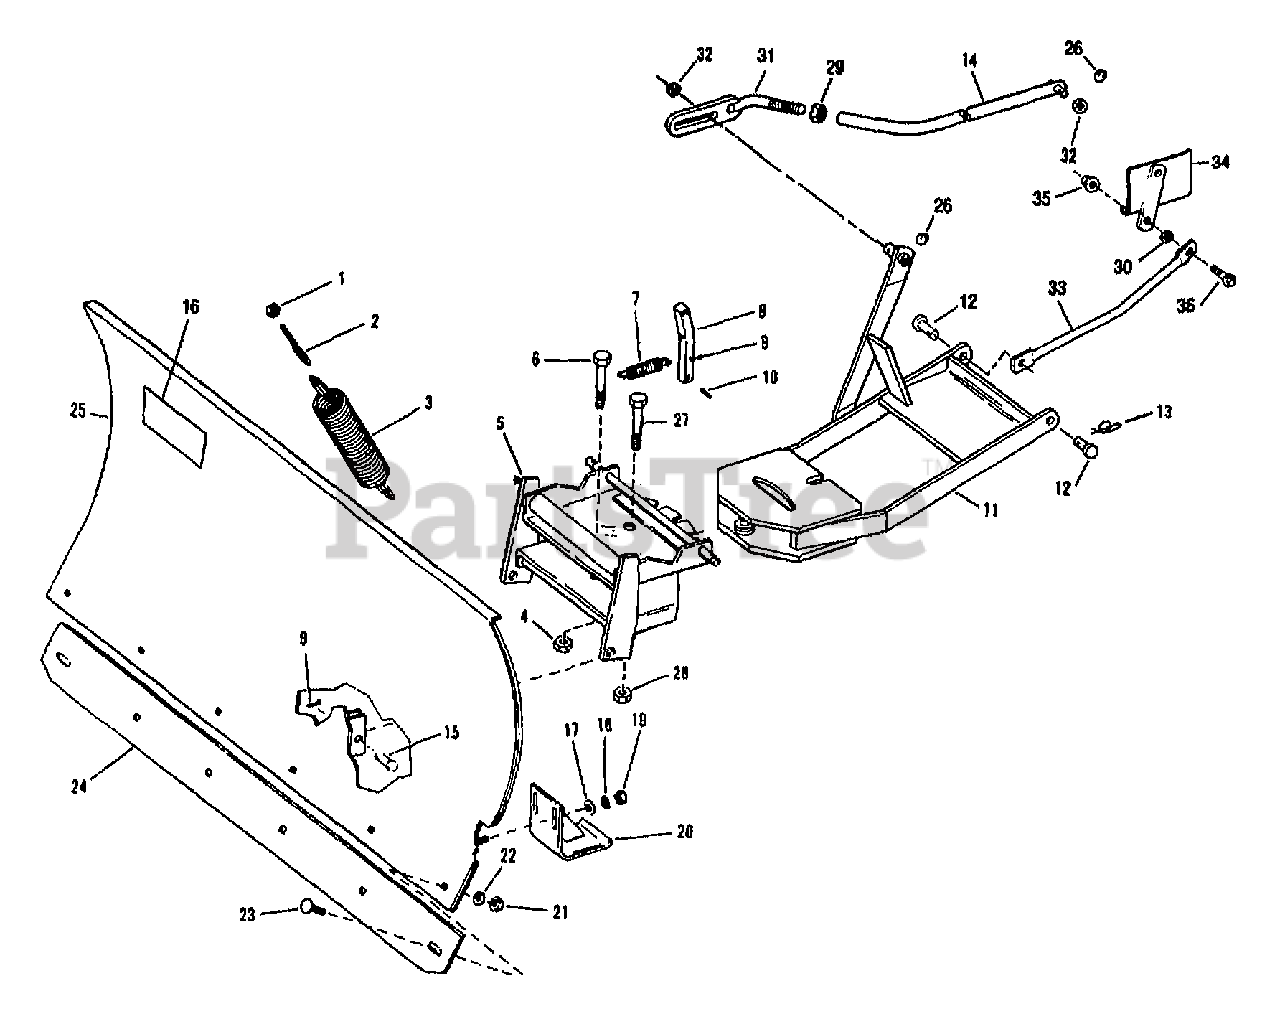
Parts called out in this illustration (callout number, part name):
1	NUT-TOP/LK 5/16-18 ZP
2	BOLT-EYE 5/16-18X2.75 ZP
4	NUT-LOCK
5	ASSM-PIVOT PLATE
6	SCR-HH 5/8-11X3.0 G5
7	SPRING
8	PIN-LATCH
9	PIN-COTTER .125 X .75 ZP
10	PIN-DRIVE .125X1.0
12	PIN-CLEVIS
13	RING-COTTER
14	ASSM-LIFT TUBE
15	PIN-CLEVIS .5X1.06 ZP
16	DECAL-LOGO
17	WASHER-FLAT 3/8 SAE
18	WASHER-LK .375 @ DEPL
19	NUT-HEX 3/8-16 ZP
20	SHOE-SKID
21	NUT-HEX 5/16-18 ZP
22	WASHER-LK .312 ZP
23	SCR-CARR 5/16-18X1.0 G2 ZP
24	BLADE-SCRAPER
26	RING-CIRCLE COTTER
27	SCR-HH 3/8-16X2.75 G5 ZP
28	NUT-LOCK 3/8-16
30	(BUY LOCAL)
31	ASSM-LIFT ROD
32	WASHER-1.06X.531X.1 ZP
33	ASSM-STRUT SUPPORT
34	ASSM-BRKT RH
35	NUT-HFLK 3/8-16 ZP
36	SCR-HFLK 3/8-16X1.00 ZP
